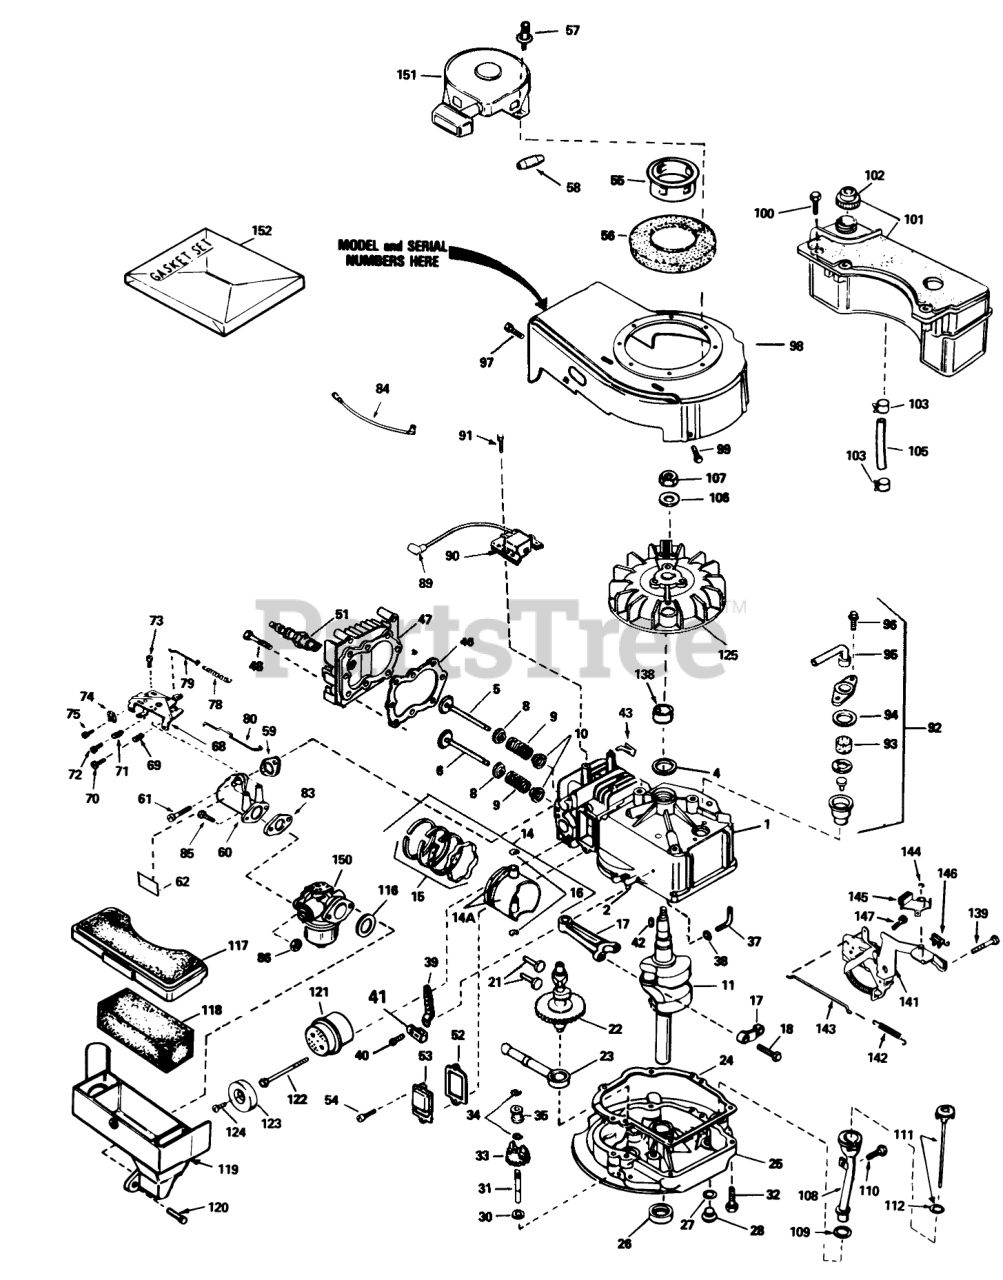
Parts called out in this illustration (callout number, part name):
1	Cylinder Assy. (Incl. #2 & 4)
2	Pin-Dowel
4	Seal-Oil
5	Valve-Intake (Std.)(Incl. #10
5	Valve-Intake (1/32" Oversize)(Incl. #10)
6	Valve-Exhaust (Std.)(Incl. #10)
6	Valve-Exhaust (1/32" Oversize)(Incl. #10)
8	Cap-Upper Valve Spring
9	Spring-Valve
10	Cap-Valve, Spring
11	Crankshaft
14	Piston-Pin & Ring Assy. (Std.)(Incl. #14A, 15 & 16)
14	Piston-Pin & Ring Assy. (.010 Oversize)(Incl. #14A, 15 & 16)
14	Piston-Pin & Ring Assy. (.020 Oversize)(Incl. #14A, 15 & 16)
14A	Piston & Pin Assy. (Std.)(Incl. #16)
14A	Piston & Pin Assy. (.010 Oversize)(Incl. #16)
14A	Piston & Pin Assy. (.020 Oversize)(Incl. #16)
15	Piston Ring Set Std.
15	Piston Ring Set .010 O.S.
15	Piston Ring Set .020 O.S.
16	Ring-Retaining, Piston Pin
17	Rod Assy.-Connecting (Incl. #18)
18	Bolt-Rod, Connecting
21	Lifter-Valve
22	Camshaft(Mech.Comp. Release)
23	Oil Pump ASM
24	Gasket, Mounting
25	Flange Assy.-Mounting (Incl. #26, 27, 28 & 31)
26	Seal Oil
27	Gasket-Oil Drain
28	Plug Oil Drain
30	Washer-Flat
31	Shaft-Governor
32	Screw (1/4-20 x 1-1/4)
33	Gear Assy.-Governor (Incl. #30)
34	Ring-Retaining
35	Spool-Governor
37	Rod-Governor (Incl. #38)
38	Washer-Flat
39	Governor Lever
40	Screw
41	Clamp-Lever, Governor
42	Key-Flywheel
43	Clip-Wire
46	Gasket-Cylinder Head
47	2025A67 ADD.ASSEMBL
48	Screw (5/16-18x1-1/2)
51	Plug, Spark (Autolite 458, Champion J-19LM or equiv.)
52	Gasket-Breather
53	Cover-Valve
55	Cup-Starter
56	Screen-Starter
57	Pop Rivet (Can be purchased locally)
58	Retainer-Starter Rope
59	Gasket-Intake
60	Pipe-Intake (Incl. #59)
61	Screw (1/4-20 x 1)
62	Decal-Primer
68	Control Assy.-Remote Speed (Incl. #69-72)
69	61709/GIL1515A/95-5
70	Screw
71	Spring-Compression
72	Screw
73	Screw (10-24 x 9/16)
74	Conduit
75	Screw (10-32 x 3/8)
78	Spring Governor
79	2035A67 ADD.ASSEMBL
80	Link-Throttle
83	Gasket
84	Ground Wire
85	Screw (1/4-28 x 7/8)
86	Nut and Lock Washer (1/4-28)
89	Cover-Spark Plug
90	Lamination & Coil Assy. (Solid State)(Incl. #89)
91	Screw
92	Breather Assy. (Incl. #93-96)
93	Element-Breather
94	Gasket-Breather
95	Tube, Breaker
96	Screw (10-24 x 9/16)
97	Screw (10-24 x 9/16)
98	Housing-Blower
99	Screw (1/4-20 x 1/2)
100	Screw (10-32 x 35/64)
101	Tank Assy.-Fuel (Incl. #102)
102	Cap-Fuel
103	Clamp-Line, Fuel
105	Line-Fuel
106	Washer-Belleville
107	Nut-Flywheel
108	Tube-Oil Fill
110	Screw (10-32 x 1/2)
111	Dipstick-Oil (Incl. #112)
116	Gasket-Cleaner, Air
117	Cover Air Cleaner
118	Filter-Air Cleaner
119	Body Air cleaner
121	Muffler (Incl. #122)
123	Cover-Muffler
124	Screw
125	Flywheel
139	Screw (1/4-20 x 3/8)
141	Bracket Assy.
142	Spring-Extension
143	Link-Control
144	Ring-Retaining
145	Lever-Brake
146	Terminal
147	Screw-Hex. Hd.
150	Carburetor (Incl. #83)
151	tarter-Rewind
152	Gasket Set
